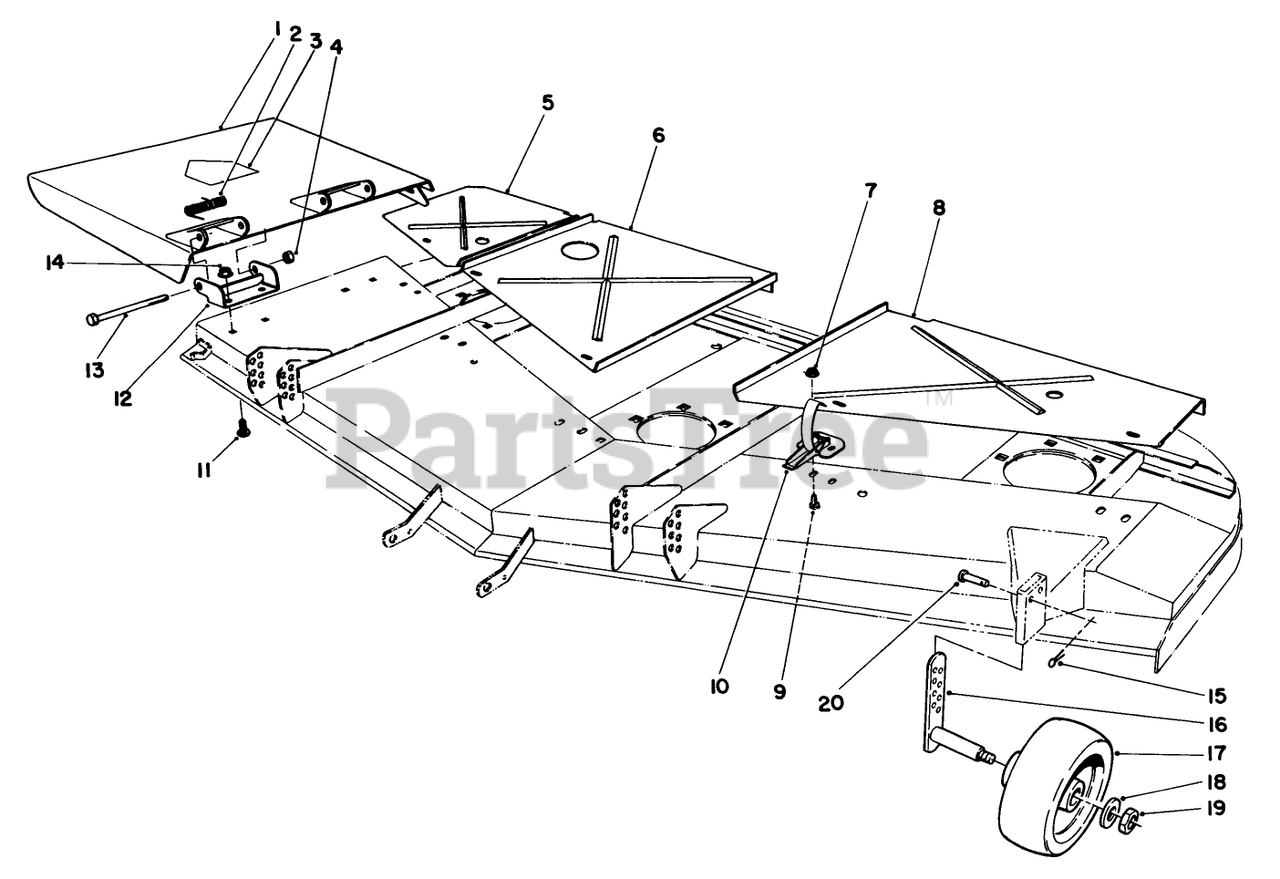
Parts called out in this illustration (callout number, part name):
1	Deflector Assembly (Incl. Ref. #3)
2	SPRING
3	DECAL-DANGER
4	NUT-HEX
5	Cover-Deck R.H.
6	Cover-Deck Center
7	NUT-LOCK, FLANGE
8	Cover-Deck L.H.
9	SCREW-HWH
10	CLAMP-SLOTTED
11	SCREW-CARR
12	Bracket-Hinge
13	SCREW-HH
14	NUT-HHF, WHIZ
15	PIN-HAIR
16	GAGE-WHEEL
17	WHEEL-GAGE
18	WASHER-FLAT
19	NUT-LOCK, NI
20	PIN-CLEVIS
